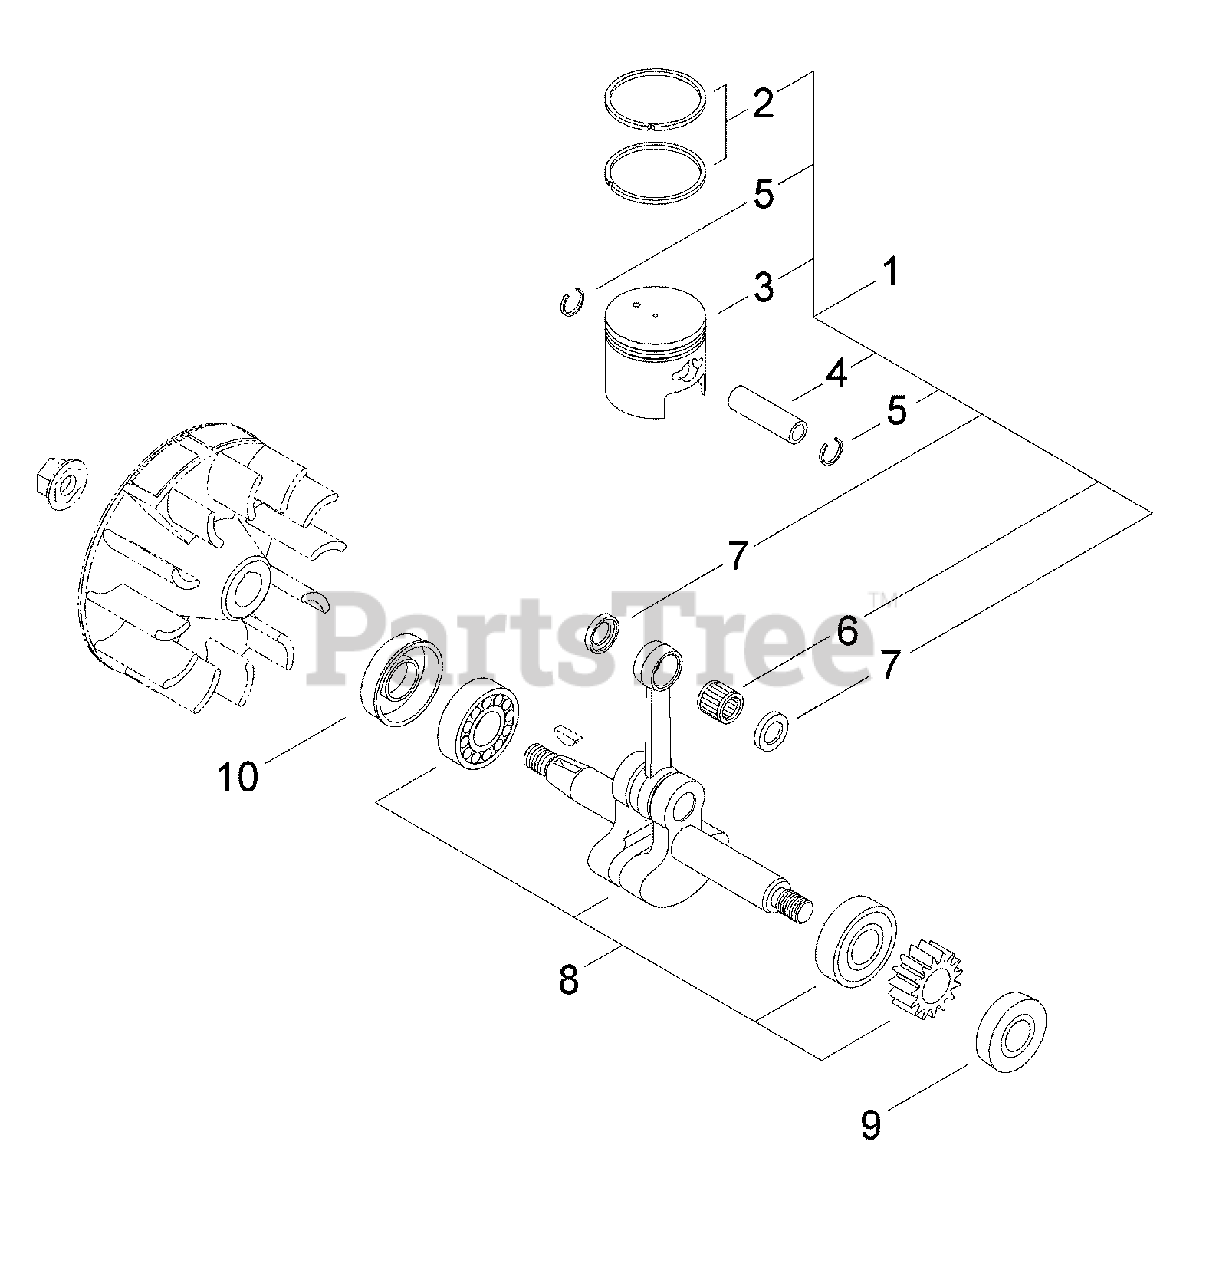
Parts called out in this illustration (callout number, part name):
1	PISTON KIT
2	RING, PISTON
3	PISTON
4	PIN, PISTON
5	RING, RETAINING
6	BEARING, NEEDLE
7	WASHER, THRUST - 10
8	CRANKSHAFT ASSY
9	SEAL, OIL - 12
10	SEAL, OIL
